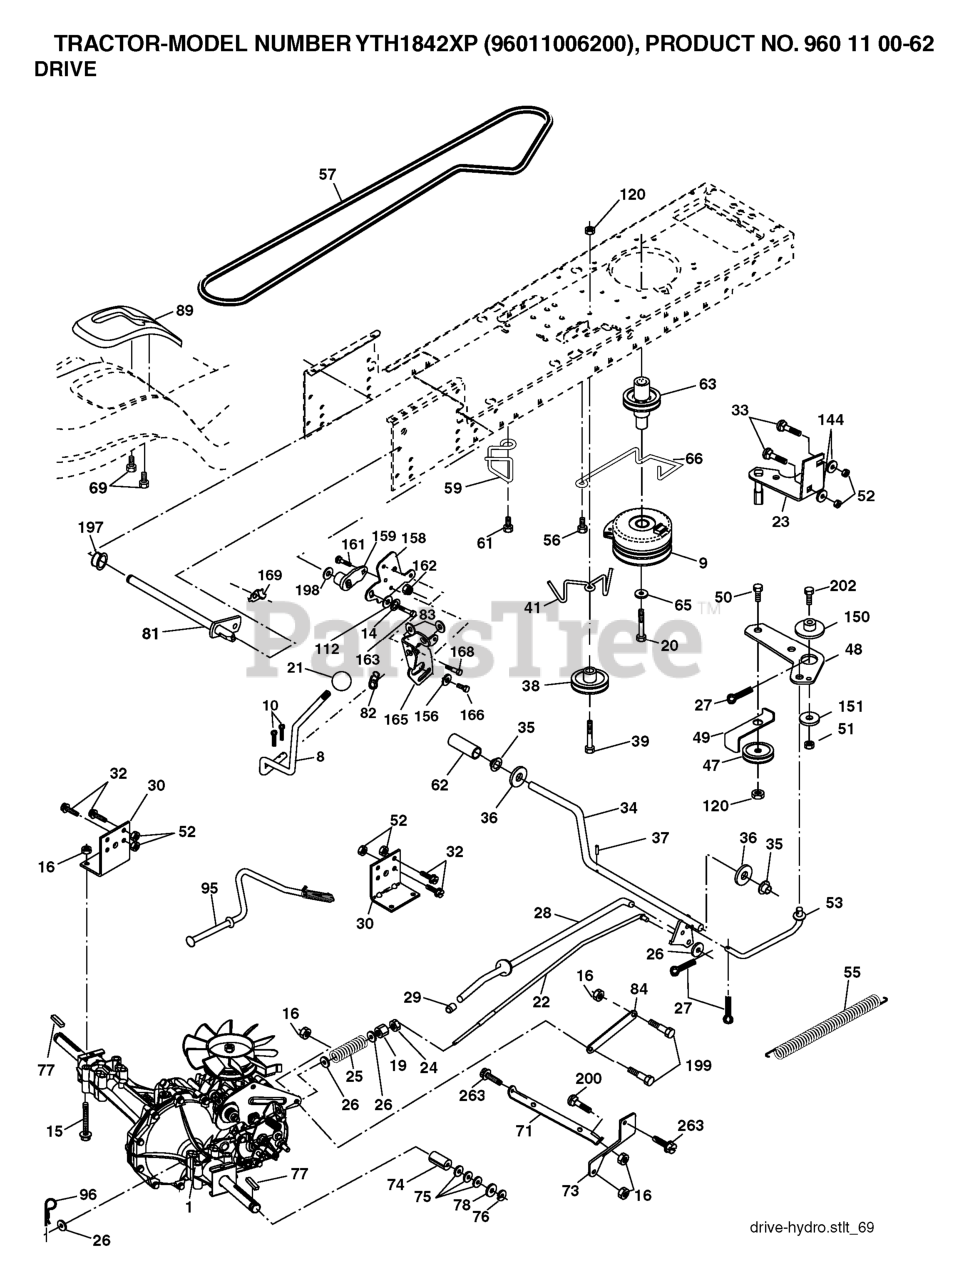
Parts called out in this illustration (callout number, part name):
8	ROD SHIFT FENDER ADJUST STLT
9	ELECTRIC CLUTCH
10	PIN COTTER
14	LOCKWASHER
15	BOLT HEX 5/16-18 GR 5
16	NUT.71038.31-18.HEX.NYLOCK
19	NUT
20	BOLT HEX
21	KNOB.DUCKHEAD.1/2
22	ROD BRAKE HYDRO
24	NUT
25	SPRING ROD LT
26	WASHER
27	COTTER PIN
28	ROD, PARKING BRAKE
29	PLUNGER CAP
30	BRKT, TRNSXLE MNT 20"
32	BOLT
33	RP BOLT 5/16-18 X3/4 ZN/YEL GR
34	SHAFT, FOOT PEDAL
35	BEARING.NYLON
37	DRIVE PIN
38	PULLEY IDLER COMPOSITE
41	KEEPER, BELT IDLER
47	IDLER PULLEY
48	BELLCRANK, CLUTCH
49	RETAIN BELT
50	BOLT.3/8-16X1.50
52	LOCKNUT
53	LINK, CLUTCH LT
55	SPRING, RETURN LT
56	SCREW.3/8-16
57	DRIVE BELT, LTH & YTH TRACTORS
59	KEEPER, BELT CENTER
61	SCREW 3/8-16X.875
62	COVER, PEDAL (1 2)
63	PULLEY, ENGINE
65	LOCKWASHER
66	KEEPER BELT ENGINE
69	SCREW.HI-LO.CONSOLE
71	STRAP TORQUE LH HYDRO
73	STRAP TORQUE RH HYDRO
74	SPACER AXLE
77	SQUARE KEY
81	SHAFT ASM CROSS TAPERED
82	SHIFT SPRING
83	WASHER
84	LINK TRANSAXLE
89	CONSOLE SHIFT STL AUTO
90	NUT.PUSH.3/16
95	CONTROL ASM. BYPASS HYDRO
96	RETAINER M
120	NUT LOCK FLG 3/8-16 UNC
144	Washer 11/32 x 5/8 x 16 Ga SD
150	SPACER, RETAINER
151	WASHER 12/32X2X10GA
156	WASHER.SRRTD.5/16
158	BRACKET
159	RB HUB.SHIFT
161	BOLT
162	NUT.CROWNLOCK.1/4
165	RP BRACKET
166	CAPSCREW.HXHD.FLG.5/16-18X.625
168	BOLT.SHOULDER.5/16-18X
169	PLATE.FASTENING.CROSS.SHAFT
197	NYLINER SNAP 5/8" ID
198	WASHER.NYL.7/8IDX.105"HYD CR
199	BOLT SHOULDER 5/16-18 UNC
263	SCREW, 3/8-16X3/4
